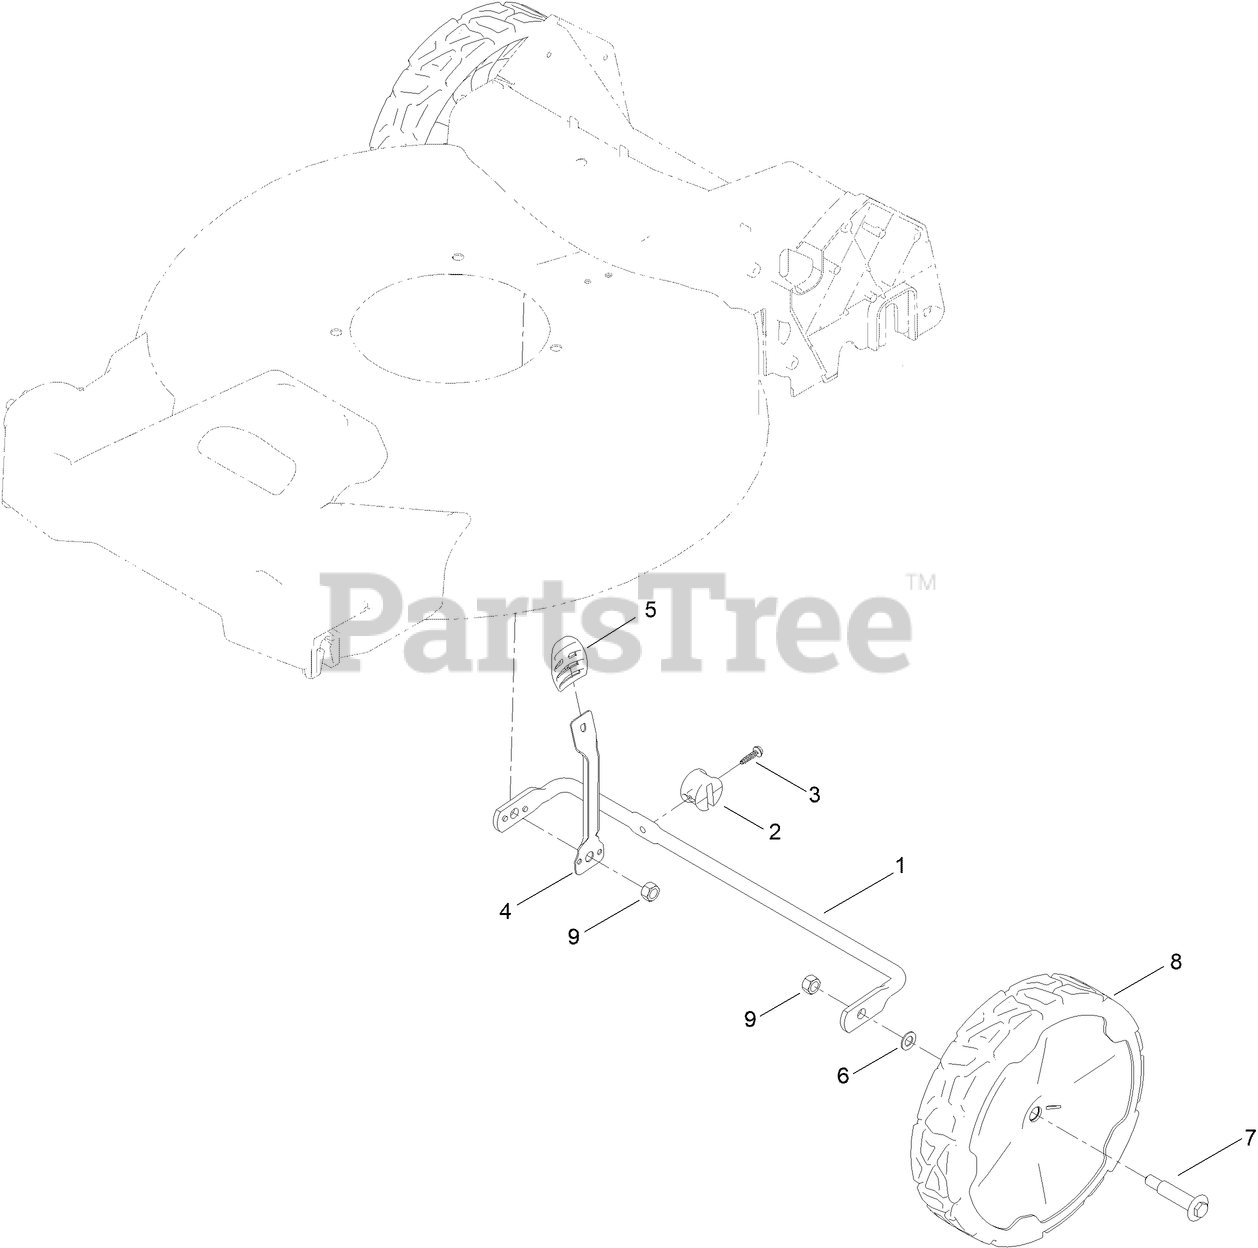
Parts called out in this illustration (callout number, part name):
1	AXLE-REAR
2	STOP-AXLE
3	SCREW-HWH
4	ARM-SPRING, HP
5	KNOB-LEVER, HOC
6	WASHER
7	BOLT-SHOULDER
8	ASM-9.65" WHEEL, BUSHINGS
9	LOCKNUT
